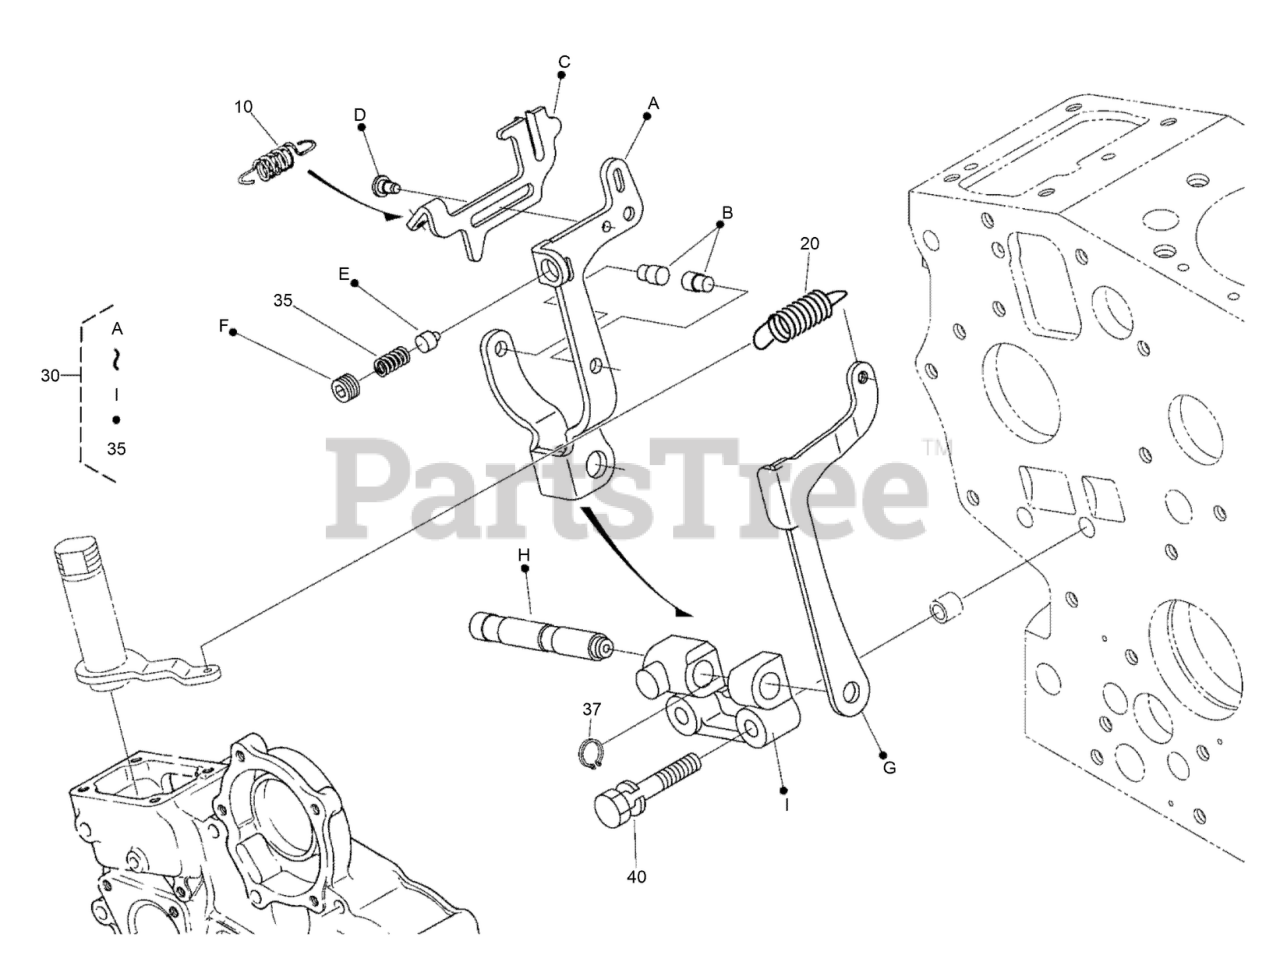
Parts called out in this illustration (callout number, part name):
10	SPRING(START)
20	SPRING-GOVERNOR
30	FORK LEVER ASM
35	SPRING
37	CIR-CLIP,EXTERNAL
